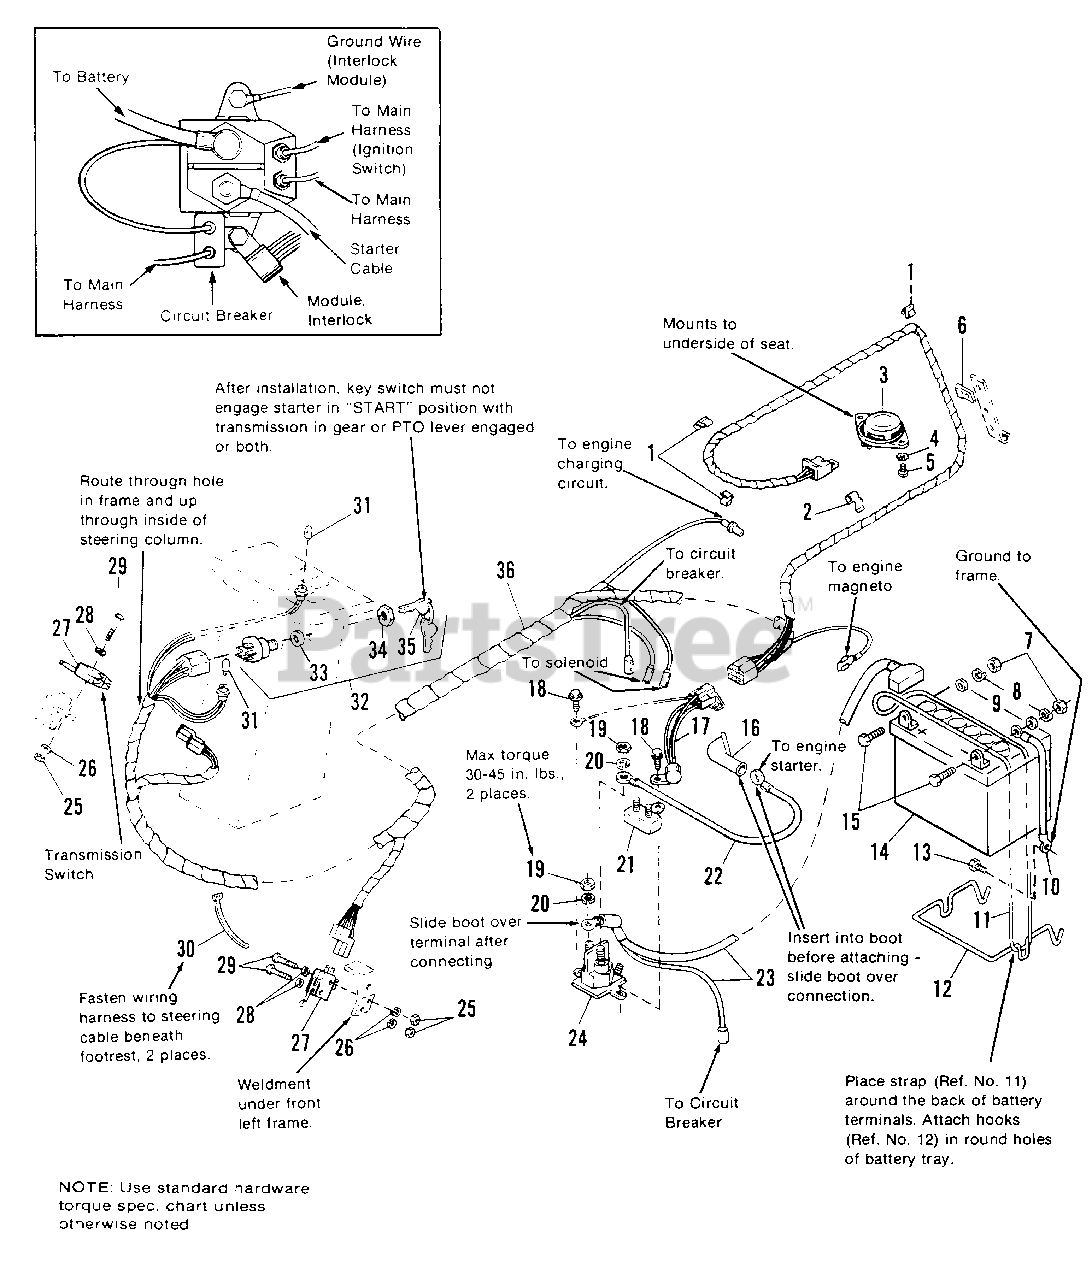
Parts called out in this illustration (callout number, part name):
1	CLIP, Wire
3	SWITCH, Seat
4	LOCKWASHER, Ext., 1/4
5	SCREW, Rd. Hd., 1/4-20 x 1/2
6	CLAMP, Wire
7	NUT, Hex, 1/4-20
8	LOCKWASHER, 1/4
9	WASHER, 1/4
10	CABLE ASSY. (Battery Ground)
11	STRAP, Battery
12	BRACE, Battery Hold Down
13	SCREW, Taptite, 5/16 x 1/2 (Zinc Pltd.)
14	BATTERY, 12V
15	CAP SCREW, Hex, 1/4-20 x 3/4)
16	COVER, Terminal
17	MODULE, DSI, Interlock
18	SCREW, Taptite, 1/4-20 x 3/4, Pltd.
19	NUT, Hex, 5/16-24
20	LOCKWASHER, 5/16
21	CIRCUIT BREAKER
22	CABLE ASSY., Starter
23	CABLE ASSY., (Battery Solenoid)
24	SOLENOID
25	NUT, Hex, #5-40
26	LOCKWASHER, #5
27	MICRO SWITCH, Tandem
28	WASHER, #6
29	SCREW, Rnd. Hd., #5-40 x 1-1/2
30	CABLE TY-WRAP
31	LAMP, Indicator
32	SWITCH, Ignition (Incl. Ref. Nos. 33, 34 & 35.)
33	LOCKWASHER, Int. 5/8
34	NUT, 5/8-32
35	KEYS & RING
36	WIRING HARNESS
